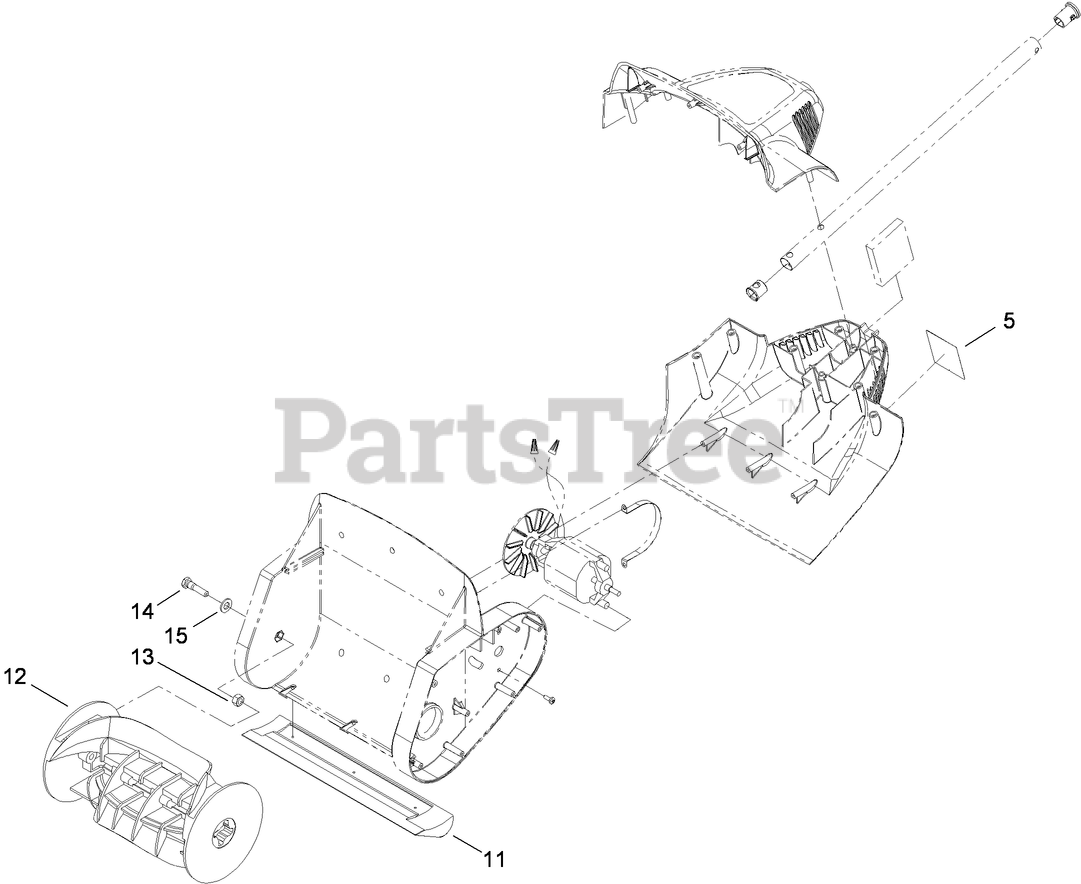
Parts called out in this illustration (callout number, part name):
5	DECAL-DANGER
11	SCRAPER-SNOW
13	NUT-LOCK
14	PIN-ROTOR
15	WASHER-PLAIN
